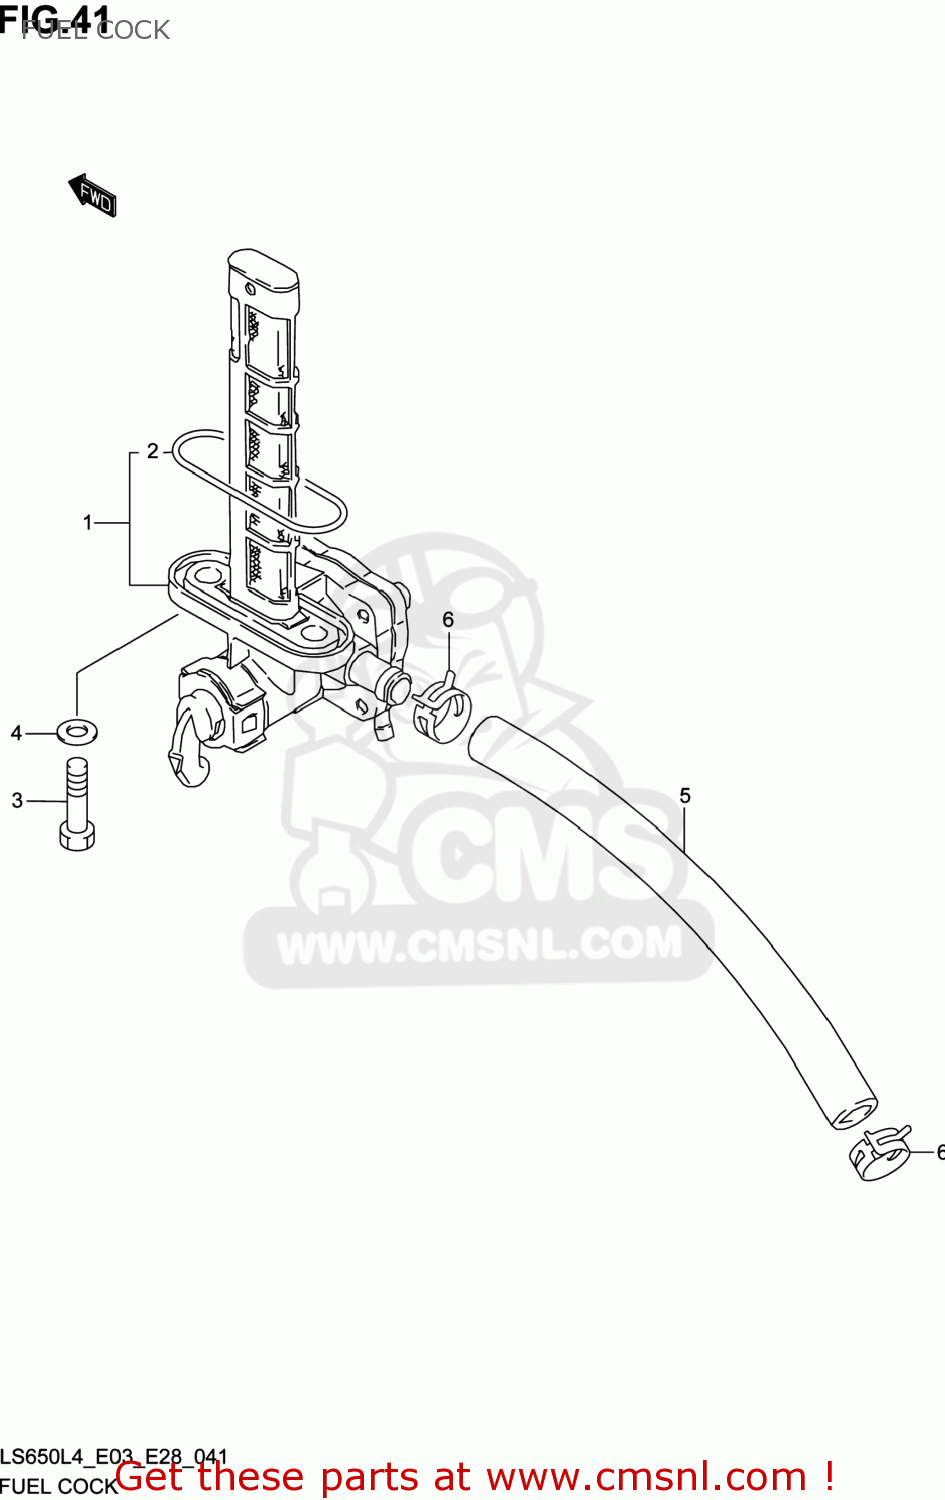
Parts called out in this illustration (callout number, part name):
1	COCK ASSY,FUEL
2	O RING,FUEL COCK
3	BOLT(6X20)
4	GASKET(6.4X11.5X0.8) (NAS)
5	HOSE(7X12X600)
6	CLIP
